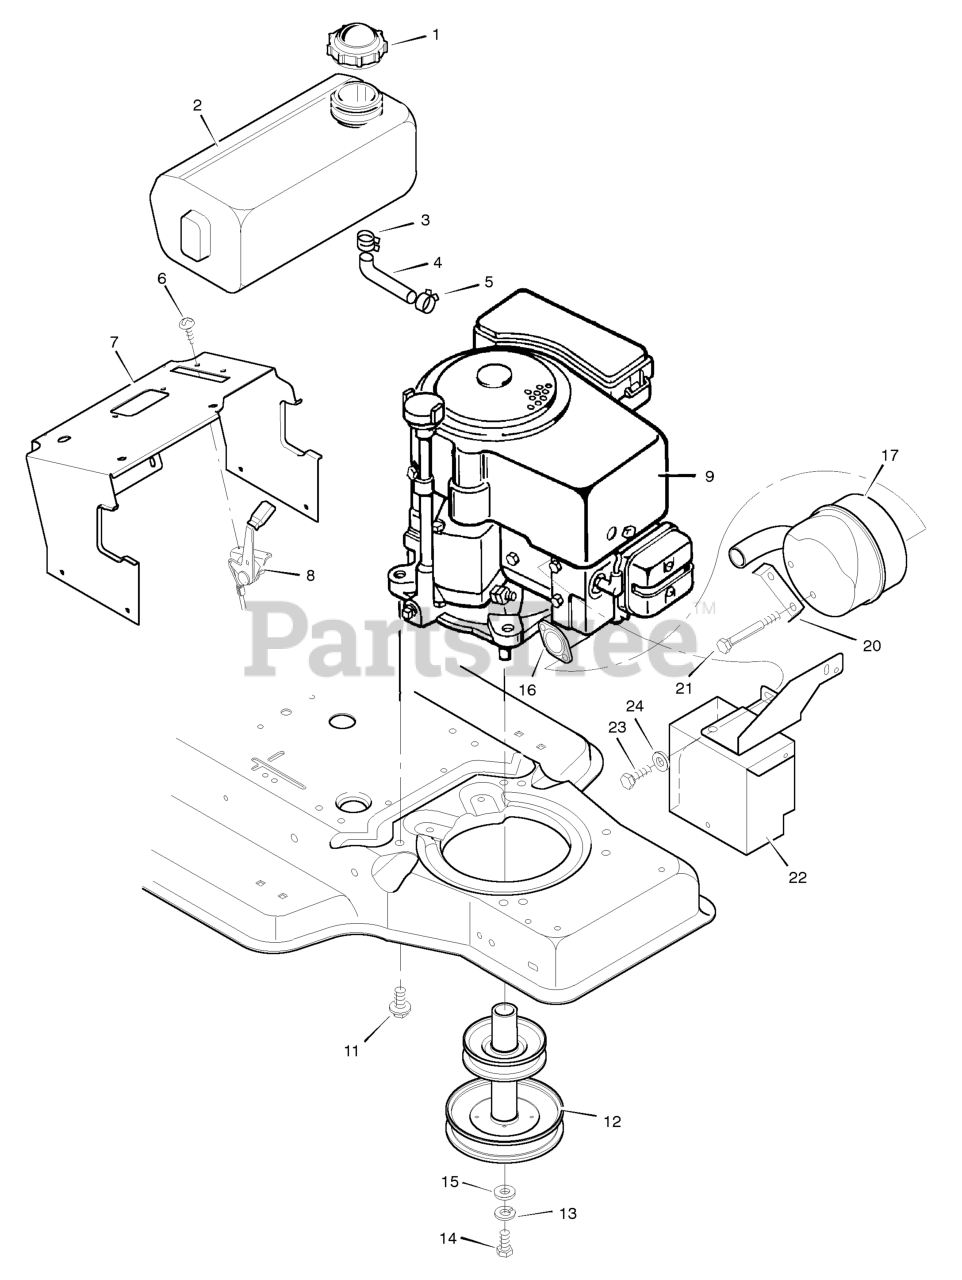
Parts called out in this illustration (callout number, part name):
1	Fuel Cap
2	Fuel Tank
3	Hose Clamp
4	Fuel Line
5	Hose Clamp
7	Support, Dash
8	Throttle Control
9	Engine *
11	Bolt, Engine Mount
12	Stack Pulley Assembly
13	Lockwasher
14	Bolt, Hex
16	GASKET, Exhaust
17	Muffler
20	Lock, Screw
22	Shield, Heat
